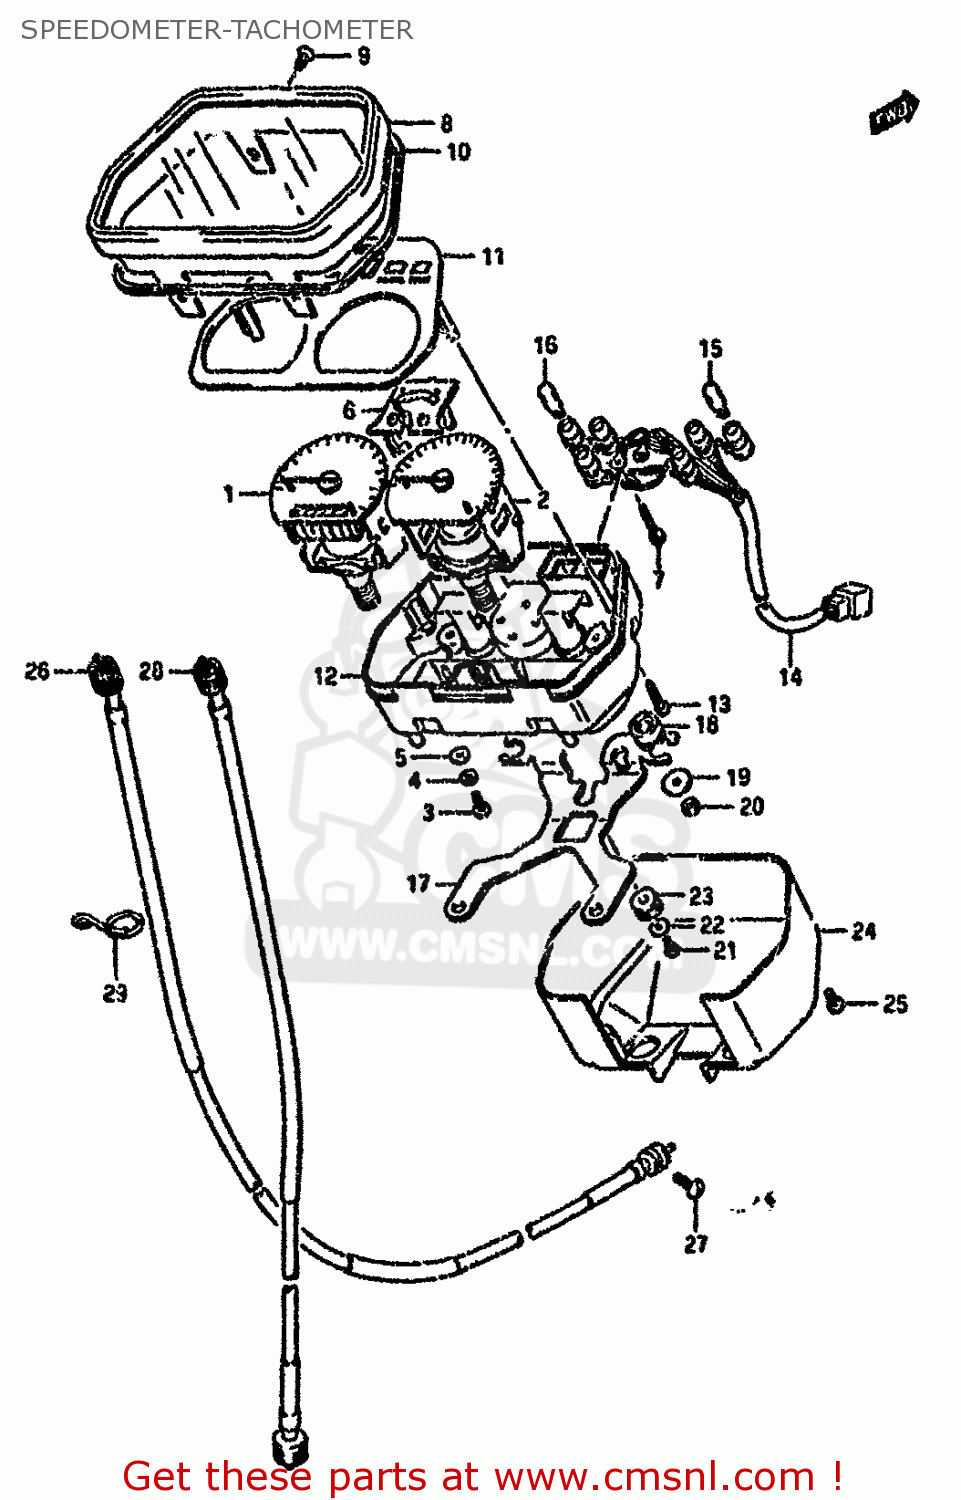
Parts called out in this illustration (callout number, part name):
1	SPEEDOMETER (KILO)
2	TACHOMETER
3	SCREW
4	WASHER,LOCK
5	WASHER
6	TEMPMETER
7	SCREW(3X22)
8	HOOD METER
9	SCREW
10	GASKET (NAS)
11	PANEL, PILOT LENS
12	CASE, METER
13	SCREW,INDICATOR
14	SOCKET
15	BULB(12V3.4W,T10)
16	BULB(12V1.7W,T10,WB121)
17	BRACKET, METER
18	CUSHION,METER NO.1
19	WASHER,METER
20	NUT
21	SCREW
22	WASHER,FUEL METER
23	CUSHION
24	COVER, LOWER
25	SCREW
26	CABLE ASSY,SPEEDOMETER
27	SCREW
28	CABLE ASSY,TACHOMETER
29	GUIDE, SPEEDOMETER CABLE
